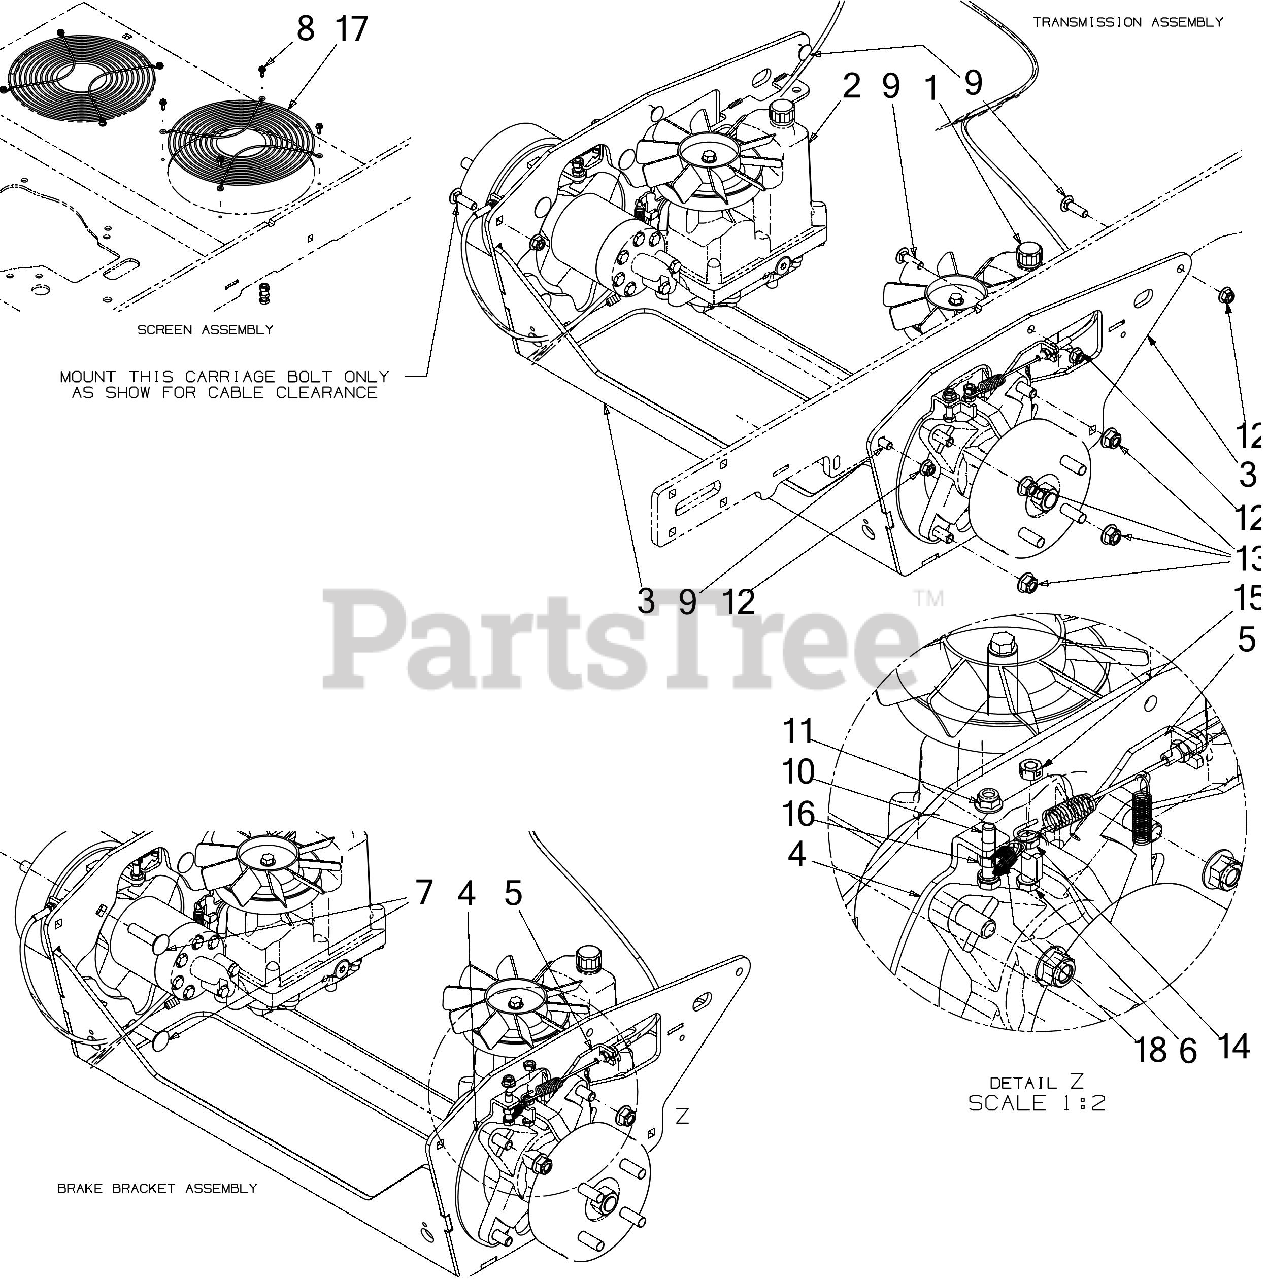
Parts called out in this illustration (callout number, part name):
1	HYDRO TRANSMISSION ASSEMBLY (RH)
2	HYDRO TRANSMISSION ASSEMBLY (LH)
3	TRANSMISSION BRACKET ASSEMBLY
4	BRAKE SPRING BRACKET
5	BRAKE CABLEB RACKET
6	SCREW 5/16-18 x 1.0 GR5
7	CARRIAGE BOLT 1/2-13 GR5
8	SCREW 10-24 x 0.500
9	CARRIAGE BOLT 3/8-16 X1.25 GR5
10	SCREW 5/16-18 x 1.5 LG
11	FLANGE LOCK NUT 5/16-18
15	HEX NUT
16	HEX NUT
18	EXTENSION SPRING .500 OD x 1.71
